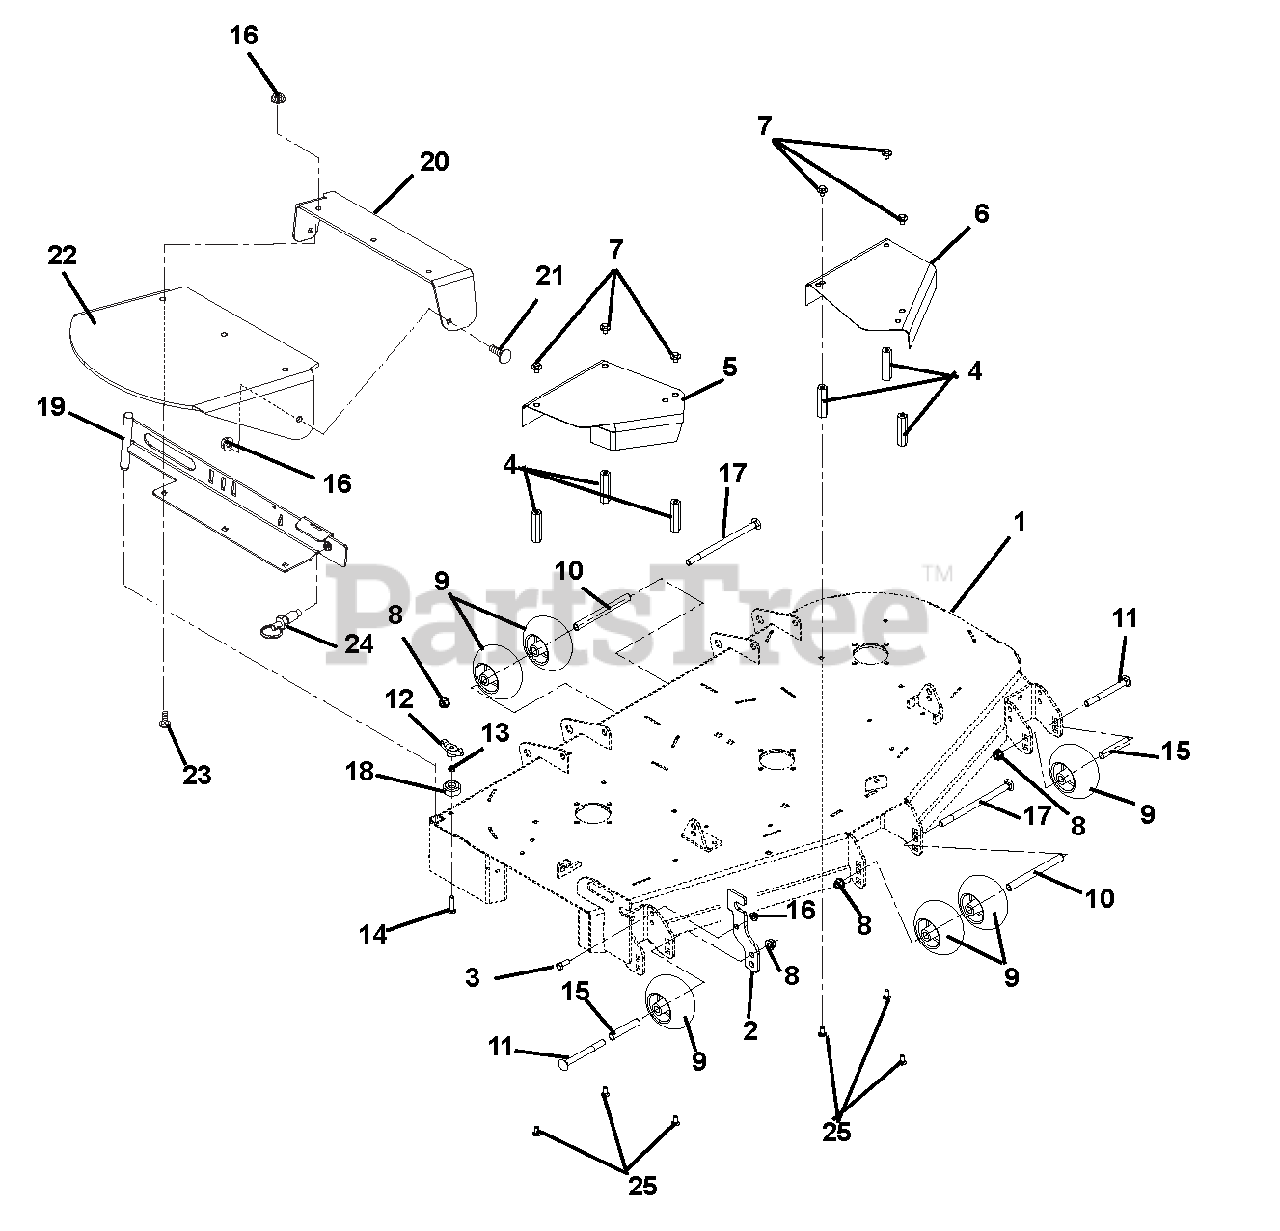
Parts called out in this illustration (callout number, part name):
1	52" 10GA SIDE DISCH DECK-ORNG
1	60" 10GA SIDE DISCH DECK -ORNG
2	BRACKET, CHUTE STORAGE
3	@BLT-HEX .38-16X1.00 GR5 YWZC
4	NUT, COUPLING .31-18 X 3.00
5	GUARD, 48"-52" RH SPNDL SHV
5	GUARD, 60" RH SPINDLE SHEAVE
6	GUARD, 44"-52" LH SPNDL SHEAVE
6	GUARD, 60" LH SPINDLE SHEAVE
7	BOLT, SEMS .31-18 X .62
8	@NUT-LK-NYL-FLG .50-13 YWZC
9	WHEEL, ANTI SCALP
10	SPACER, .510X.625X6.50
11	BLT-RDHDSQNK .50-13X5.00 GR5YZ
12	KNOB - WING .312-18 UNC
13	@NUT-LK-CTR .31-18 YWZC
14	@BLT-RDHDSQNK .31-18X1.50 G5YZ
15	SPACER, .510X.625X3.35
16	@NUT-LK-NYL-FLG .38-16 YWZC
17	@BLT-RDHDSQNK .50-13X8.50 G5YZ
18	BUMPER,RECESSED1.50X.63 W/.31
19	WMT, 52"-60" DISCH CHUTE MTG
20	SUPPORT, RUBBER DISCH CHUTE
21	@BLT-RDHDSQNK .38-16X1.00 G5YZ
22	CHUTE, RUBBER DISCHARGE
23	@BLT-RDHDSQNK .38-16X1.25 G5YZ
24	PULL PIN,.50-13THDX.310 PLNGR
25	BLT,RDHDSQNK .31-18X.75 LOCTIT
